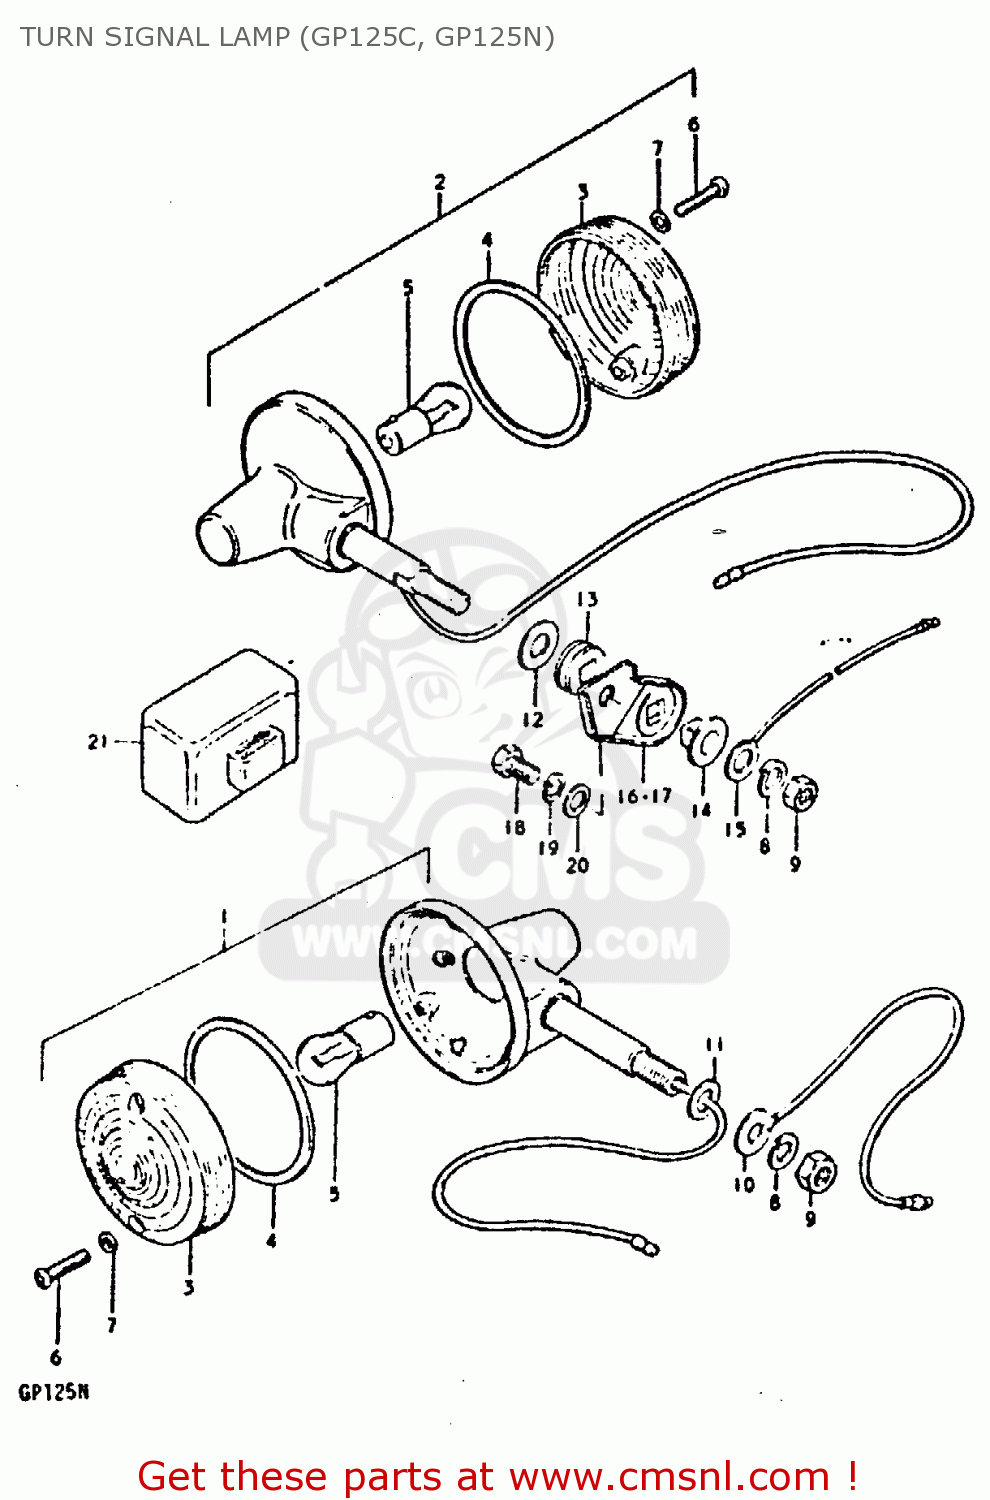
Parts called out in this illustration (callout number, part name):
8	LOCK WASHER
9	NUT
10	LEAD WIRE,EARTH
11	WASHER
20	WASHER
